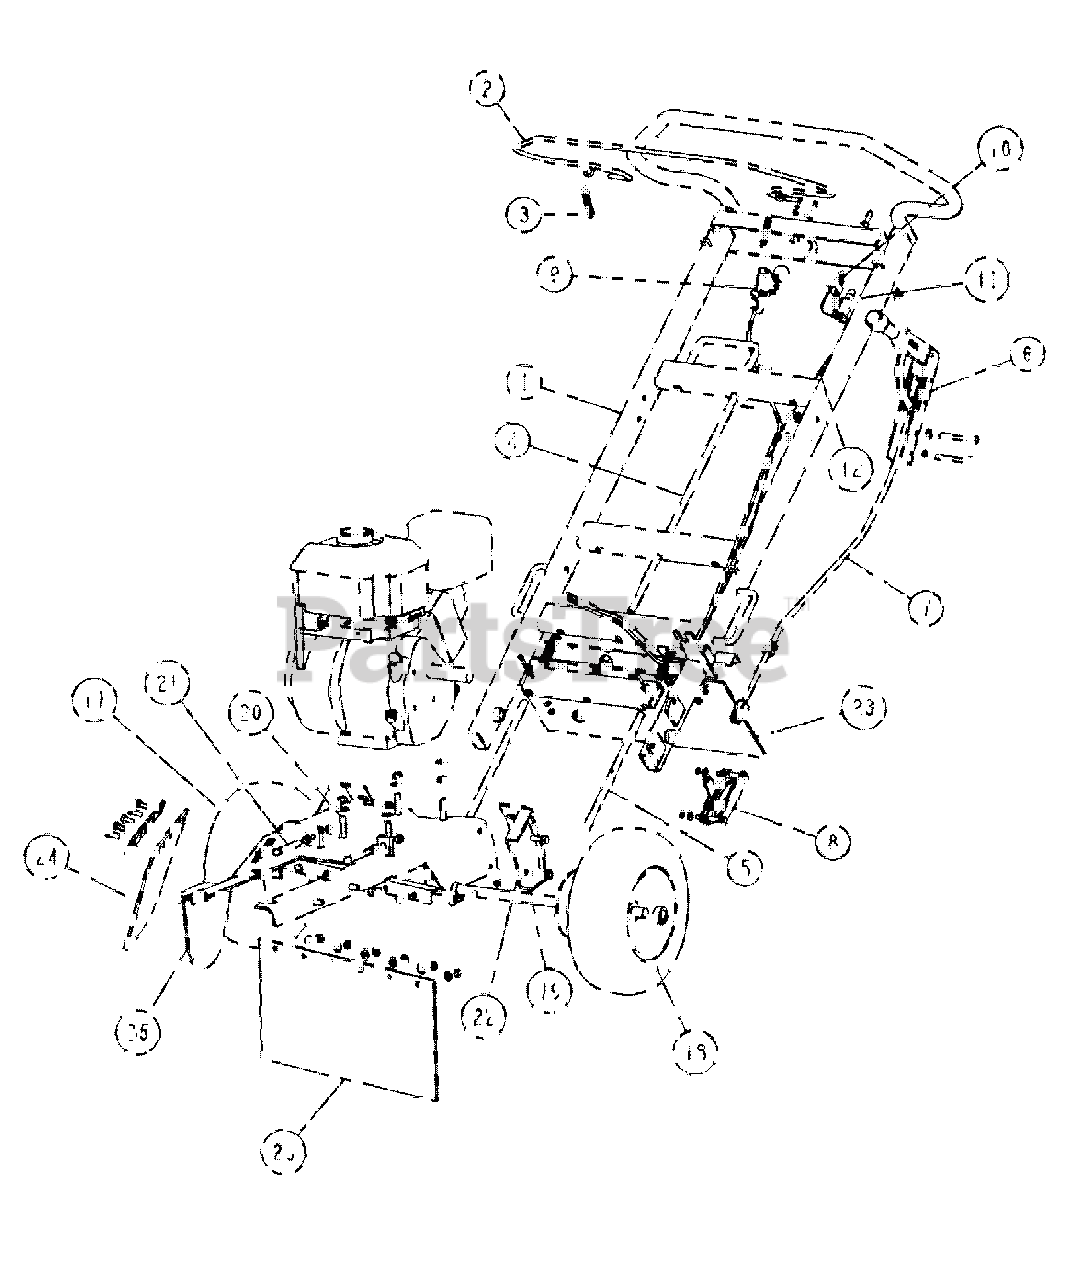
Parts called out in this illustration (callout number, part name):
1	Handle
2	Bail Assy
3	Extension spring (1 ea)
4	Handle Adjustment Lever Assembly
5	Handle Adjustment Pin Assembly
6	Brake Lever
7	Brake Cable
8	Brake Caliper Assembly
9	Throttle Cable Assembly
10	On/Off Toggle Switch
11	Plunger Switch Assembly
12	Wire Harness Assembly
17	Right Wheel
18	Left Wheel
19	Axle Assembly-Axle
20	Engine Bolt Kit
21	Jack Screw
22	Handle Adjustment Bracket
23	Rear Deflector Kit and Deck Deflector Kit
24	Right Side Deflector Kit
35	Deck, Stump Grinder
37	SG11 Decal Kit (11 hp)
38	SG13 Decal Kit (13 hp)
